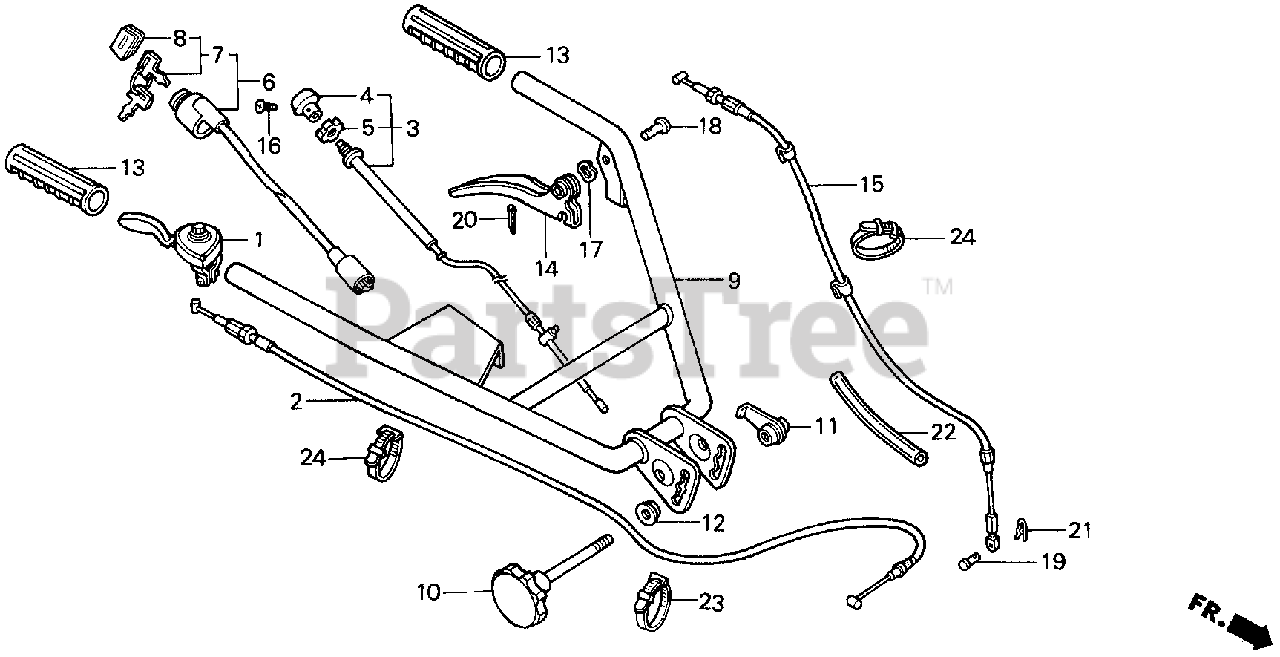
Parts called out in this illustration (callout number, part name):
1	LEVER ASSY., THROTTLE
2	CABLE, THROTTLE
3	CABLE, CHOKE
4	KNOB, CHOKE WIRE
5	NUT (14MM)
6	SWITCH ASSY., COMBINATION
7	KEY ASSY., COMBINATION SWITCH
10	ADJUSTER, HANDLE
11	NUT, HANDLE LOCK
12	NUT, SPECIAL (10MM)
13	GRIP, HANDLE
14	LEVER, CLUTCH (NOT AVAILABLE)
15	CABLE, CLUTCH
16	SCREW, PAN (2.6x6)
17	WASHER, WAVE (10MM)
18	PIN (8X18)
19	PIN (4X15.5) (NOT AVAILABLE)
20	PIN, COTTER (2.0X15)
21	PIN, LOCK (4MM)
22	BULK HOSE, VINYL (12X16X3000) (12X16X130)
23	BAND B1, CABLE
24	BAND B2, CABLE HARNESS
